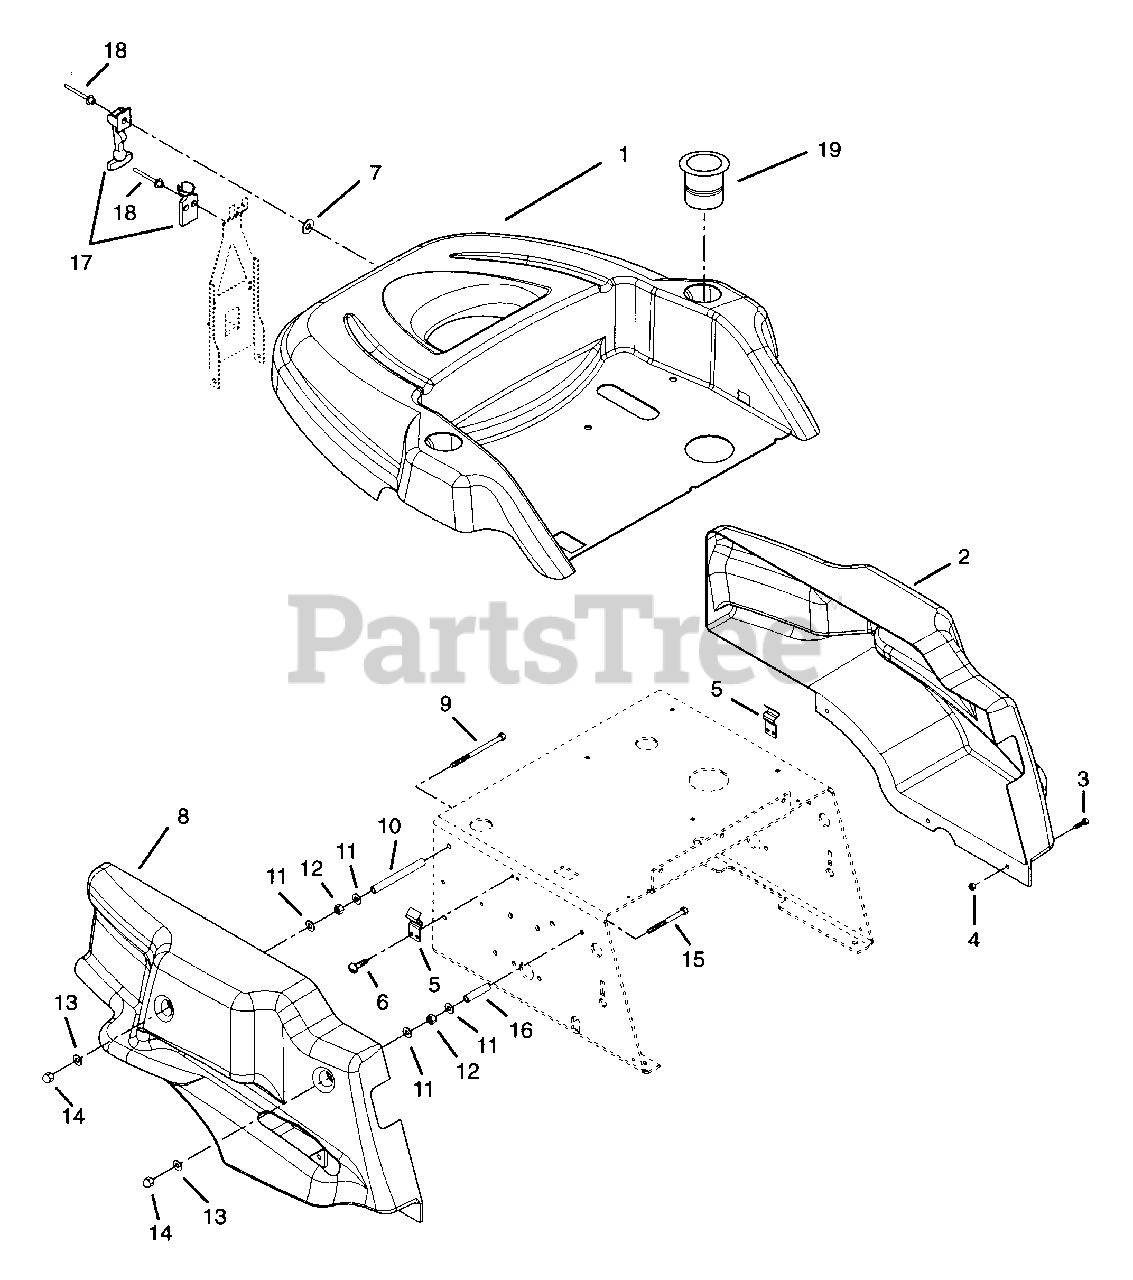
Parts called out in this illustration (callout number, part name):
1	SHROUD, TOP
2	SHROUD, SIDE LH
3	BLT-HEX .31-18X1.00 PL GR5
4	NUT-LK-NYL.312-18 PL
5	CLIP, SHROUD RETAINER
6	SCR-TAP .250-20X.50 HXSLHDPL
7	RVT-BURR .125X.505X.048
8	SHROUD, SIDE RH
9	BLT-HEX .31-18X5.50 PL GR5
10	SPACER .328X.462X4.42
11	WSHR-FL-STL .313X.875X.065
12	NUT-HEX .312-18
13	WSHR-FL-STL.312X.734X.065PL
14	NUT .31-18 LOW CROWN
15	BLT-HEX .31-18X3.00 PL GR5
16	SPACER .328X.462X1.92
17	LATCH,FLEXIBLE
18	ABA46 BLIND RIVET (AB4-6A)
19	CUPHOLDER
